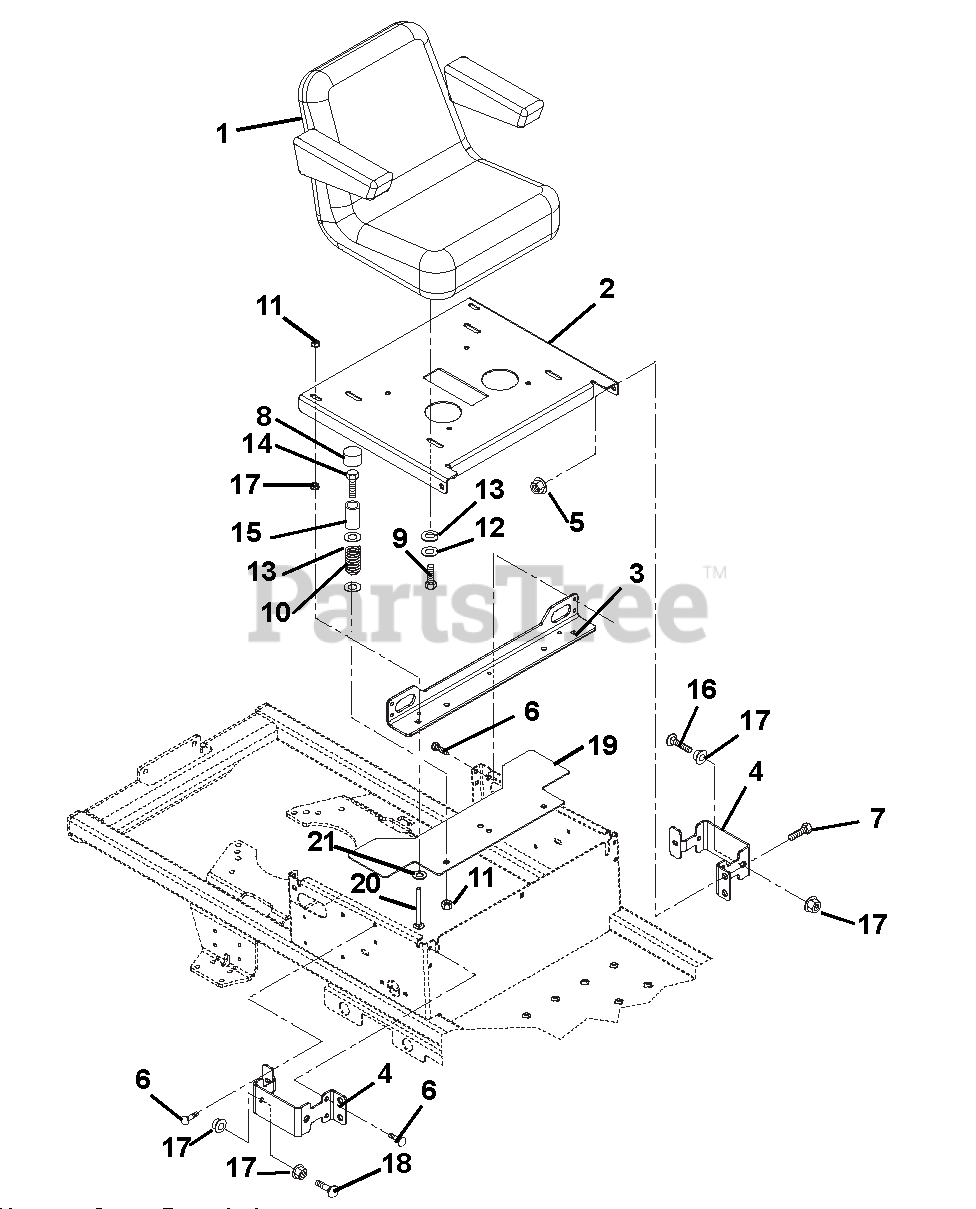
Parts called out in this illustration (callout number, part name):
1	SEAT,V-2505 MICHIGAN W/ARM
2	SEAT PLATE
3	BKT,SEAT SPRING
4	WMT, STEERING STOP
5	@NUT-LK-TOP-FLG .38-16 YWZC
6	@SCR-TAP .31-18X.50 HWH TR YWZ
7	BOLT-SHLDR .375-16X.150
8	HUB CAP
9	@BLT-HEX .31-18X1.00 GR5 YWZC
10	SPRING, SEAT
11	@NUT-LK-NYL-FLG .31-18 YWZC
12	@WSHR-LK .31X.078 REG YWZC
13	WSHR-FL-STL .328X.87X.179 YWZC
14	@BLT-HEX .31-18X2.75 GR5 YWZC
15	BSHG-SLV .334 X .502 X 1.437
16	@BLT-RDHDSQNK .31-18X2.50 G5YZ
17	@NUT-SPNLK-FLG .312-18 YWZC
18	@BLT-RDHDSQNK .31-18X1.75 G5YZ
19	GUARD,CE FINGER
20	@BLT-RDHDSQNK .31-18X3.50 G5YZ
21	WSHR-FL-STL .505X1.00X.062YWZC
